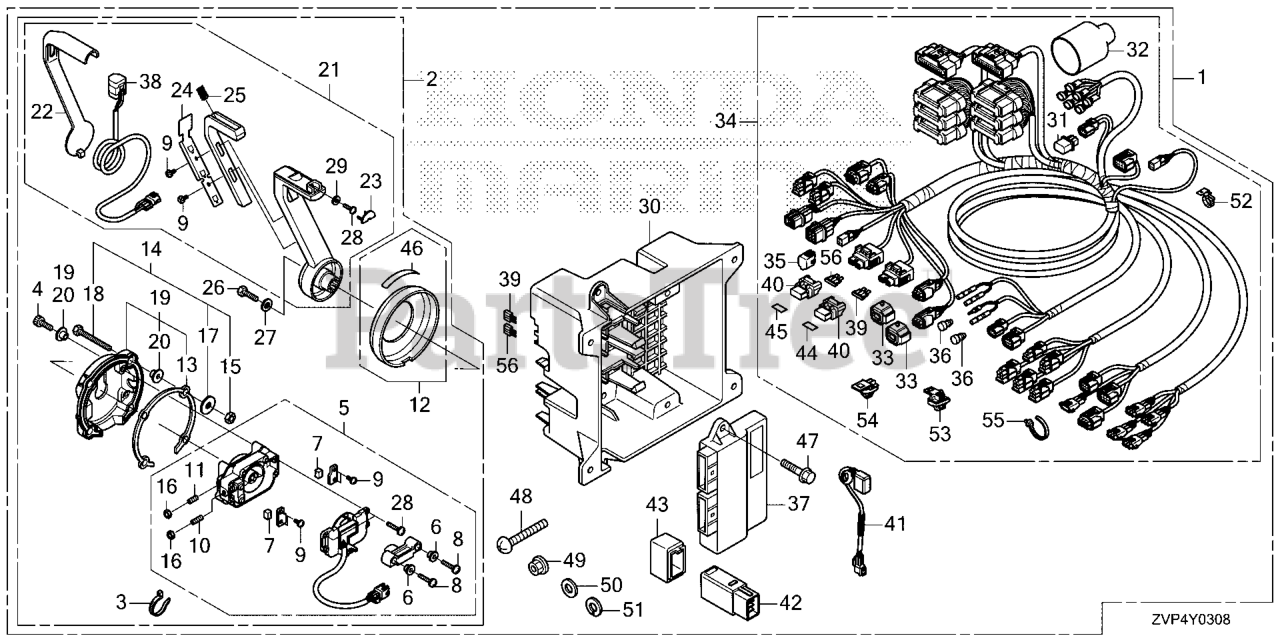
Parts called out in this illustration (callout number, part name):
1	BOX KIT, R/C
2	BOX ASSY., REMOTE CONTROL (FLUSH MOUNT)(RH)
3	BAND, NYLON
4	BOLT, SOCKET
5	HOUSING ASSY. (FLUSH MOUNT)
6	COLLAR, STOPPER
7	SHOE, BRAKE
8	SCREW
9	SCREW
10	SCREW SET
11	SCREW SET
12	COVER ASSY. (FLUSH MOUNT)
13	SHEET, WATERPROOF (FLUSH MOUNT)
14	NUT SET, MOUNTING
15	NUT, NYLON
16	NUT
17	WASHER
18	BOLT
19	BASE ASSY. (FLUSH MOUNT)
20	COLLAR, BASE
21	LEVER ASSY. (FLUSH MOUNT)
22	PANEL, LEVER (FLUSH MOUNT)
23	CAP, LEVER (FLUSH MOUNT)
24	PLATE, LEVER PANEL
25	SPRING, COIL
26	BOLT
27	WASHER
28	SCREW
29	WASHER
30	CASE, CONTROL UNIT
31	TERMINATOR ASSY.
32	COVER, CONNECTOR (NOT AVAILABLE)
33	SUSPENSION, CONNECTOR
34	CABLE, REMOTE CONTL
35	CAP, DUMMY (WPC 4P 090 M) (RED)
36	PLUG, CONNECTOR (INNER) (TROLLING CONTROL)
37	UNIT ASSY., CONTL
38	SWITCH ASSY., POWER TRIM-TILT (FLUSH MOUNT)
39	FUSE, BLADE (3A)
40	COVER ASSY., FUSE
41	RELAY ASSY., CONTROL (NOT AVAILABLE)
42	RELAY ASSY., MAIN
43	SUSPENSION, RELAY
44	LABEL, FUSE (3A)
45	LABEL, FUSE (5A)
46	MARK, FLUSH MOUNT
47	BOLT, FLANGE (6X20)
48	SCREW, PAN (5X40) DUAL QTY = (8) (SINGLE)
49	NUT, FLANGE (5MM)
50	WASHER, PLAIN (5MM)
51	WASHER, SPG (5MM)
52	HOLDER, CONNECTOR (128.6MM) (NATURAL)
53	CLIP, CONNECTOR (DARK BLUE)
54	CLIP, CONNECTOR (DARK BROWN)
55	CLIP, HARNESS BAND (145MM) (BLACK)
56	FUSE, MINI (5A)
